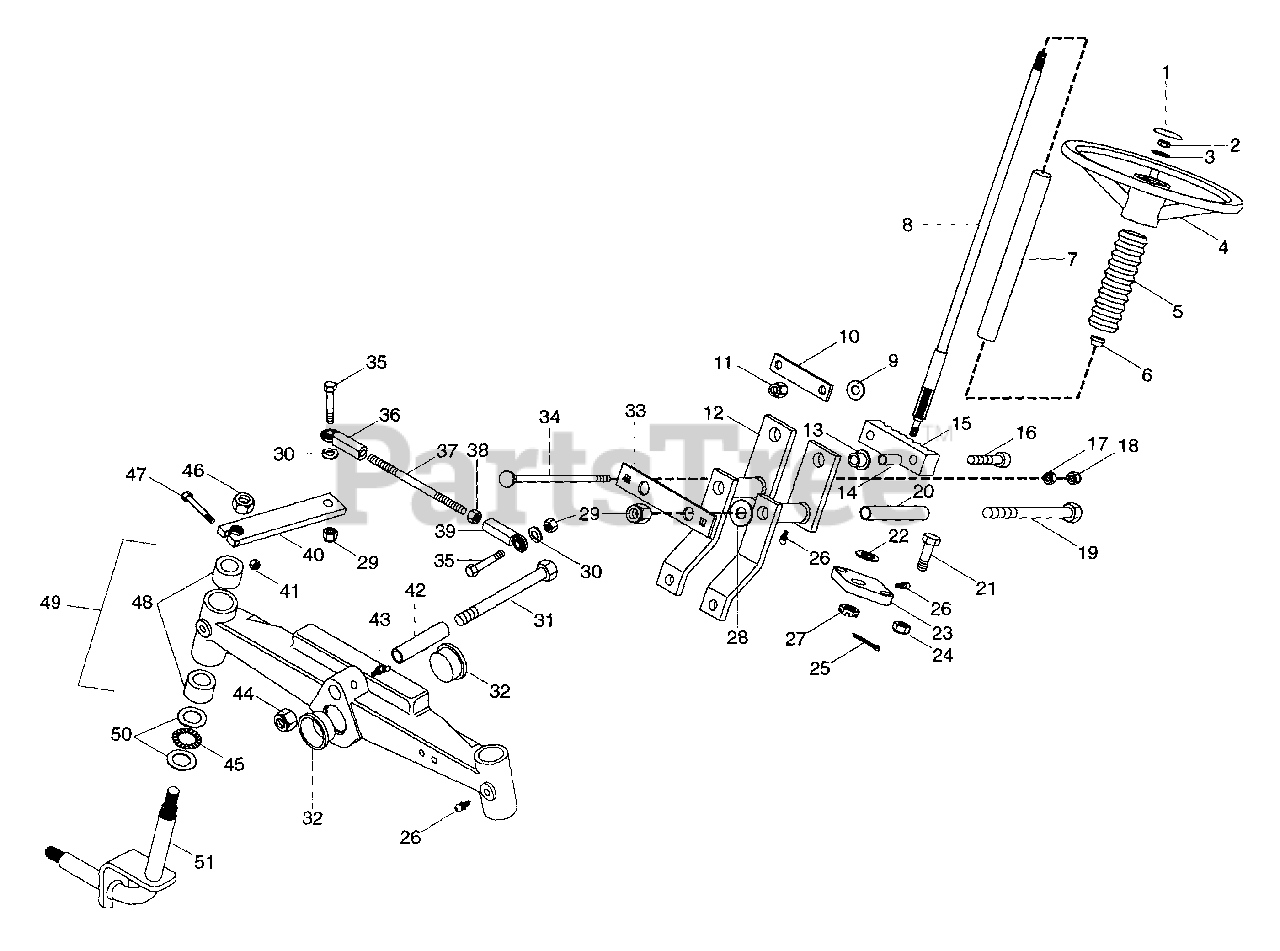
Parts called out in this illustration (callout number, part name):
1	Steering Wheel Cap
2	Nut-Jam .625-11
3	Washer-Flat-Steel .656 x 1.312 x .095
4	Steering Wheel
5	Steering Column Boot
6	Bushing-Flange .762 x 1.0 x .580 x 1.48
7	Tube, Plastic 1.0 I.D.
8	Weldment, Steering Shaft
9	Washer-Flat-Steel .375 x 1.125 x .065
10	Strap, Rack and Pinion
11	Nut-Locking-Nylon .375-16 Grade 2
12	Weldment, Steering
13	Bushing-Flange .627 x .879 x .469 x 1.120
14	Bushing, Steel .391 x .621 x .676
15	Grade, Rack
16	Screw-Cap .38-16 x 2
17	Nut-Hex .312-18 Grade 2
18	Nut-Locking-Nylon .312-18 Grade 2
19	Bolt-Hex .50-13 x 6.00
20	Sleeve, Pivot
21	Bolt-Hex .44-14 x 1.50
22	Washer-Thrust .507 x .917 x .031
23	Support, Steering Shaft
24	Nut-Locking-Hex .44-14
25	Pin-Cotter .09 x 1.0
26	Fitting-Lube .25-28 x .256
27	Nut-Hex-Slotted .500-13
28	Bearing-N-Thrust .752 x 1.24 x .093
29	Nut-Locking-Nylon .375-24 Grade 2
29	Nut-Locking-Nylon .50-13 Grade 5
30	Washer-Lock .50 Reg
31	Bolt-Hex .75-10 x 4.50
32	Cap, Front Axle
33	Plate, Adjustment
34	Bolt-Round Head Square Neck .31-18 x 5.50 Grade 2
35	Bolt-Hex .50-13 x 2.25 Grade 5
36	Rod End, Steering Right Hand Thread
37	Tie Rod, Steering
38	Nut-Jam .50-20 Grade 2
39	Rod End, Steering Left Hand Thread
40	Arm, Tie Rod Axle
41	Nut-Locking-Nylon .312-24 Grade 2
42	Tube, Axle Pivot
43	Fitting, Lube 45 Deg.
44	Nut-Locking-Nylon .75-10 Grade 2
45	Bearing-Thrust .875 x 1.427 x .078
46	Nut-Hex .625-11 Grade 2
47	Bolt-Hex .31-24 x 1.75
48	Bushing-Sleeve .866 x 1.004 x 1.000
49	Axle, Steering
50	Washer-Thrust .877 x 1.427 x .032
51	Weldment, King Pin
